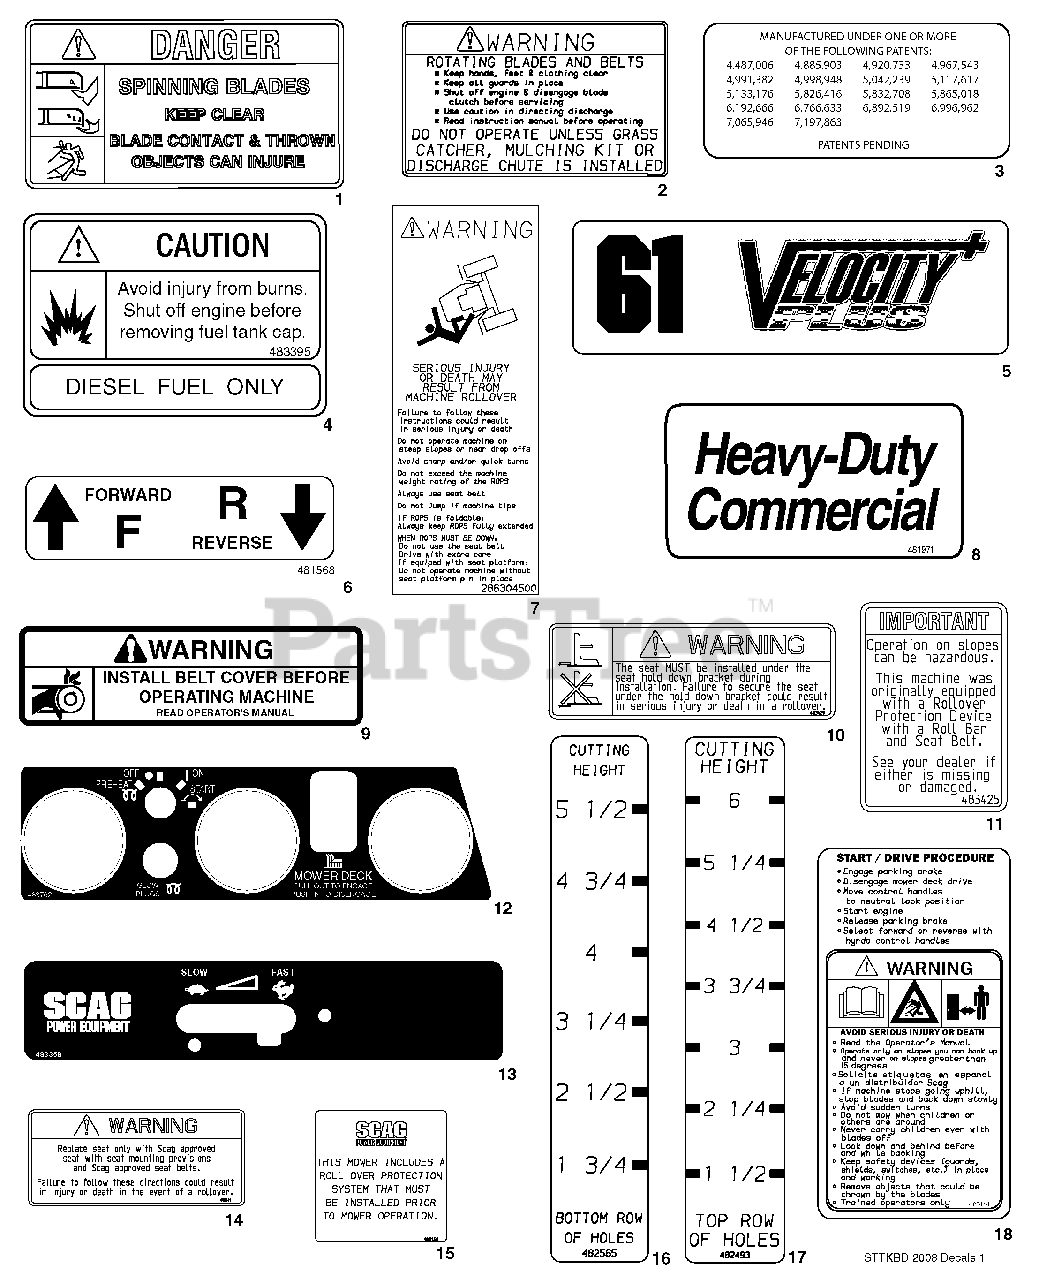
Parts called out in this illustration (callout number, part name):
1	Decal, Danger-Spinning Blades
2	Decal, Warning-Rotating Blades
3	Decal, Patents
4	Decal, Fuel Tank
5	Decal, 61" Velocity Plus
6	Decal, Traction Control
7	Decal, ROPS Warning
8	Decal, Heavy Duty Commercial
9	Decal, Belt Cover
10	Decal, Warning Seat Hold Down
11	Decal, ROPS
12	Decal, Instrument Panel - Upper (CAT)
13	Decal, Instrument Panel - Lower (CAT)
14	Decal, Seat Replacement
15	Decal, ROPS
16	Decal, Cutting Height - Lower
17	Decal, Cutting Height - Upper
18	Decal, Start/Drive Procedure
